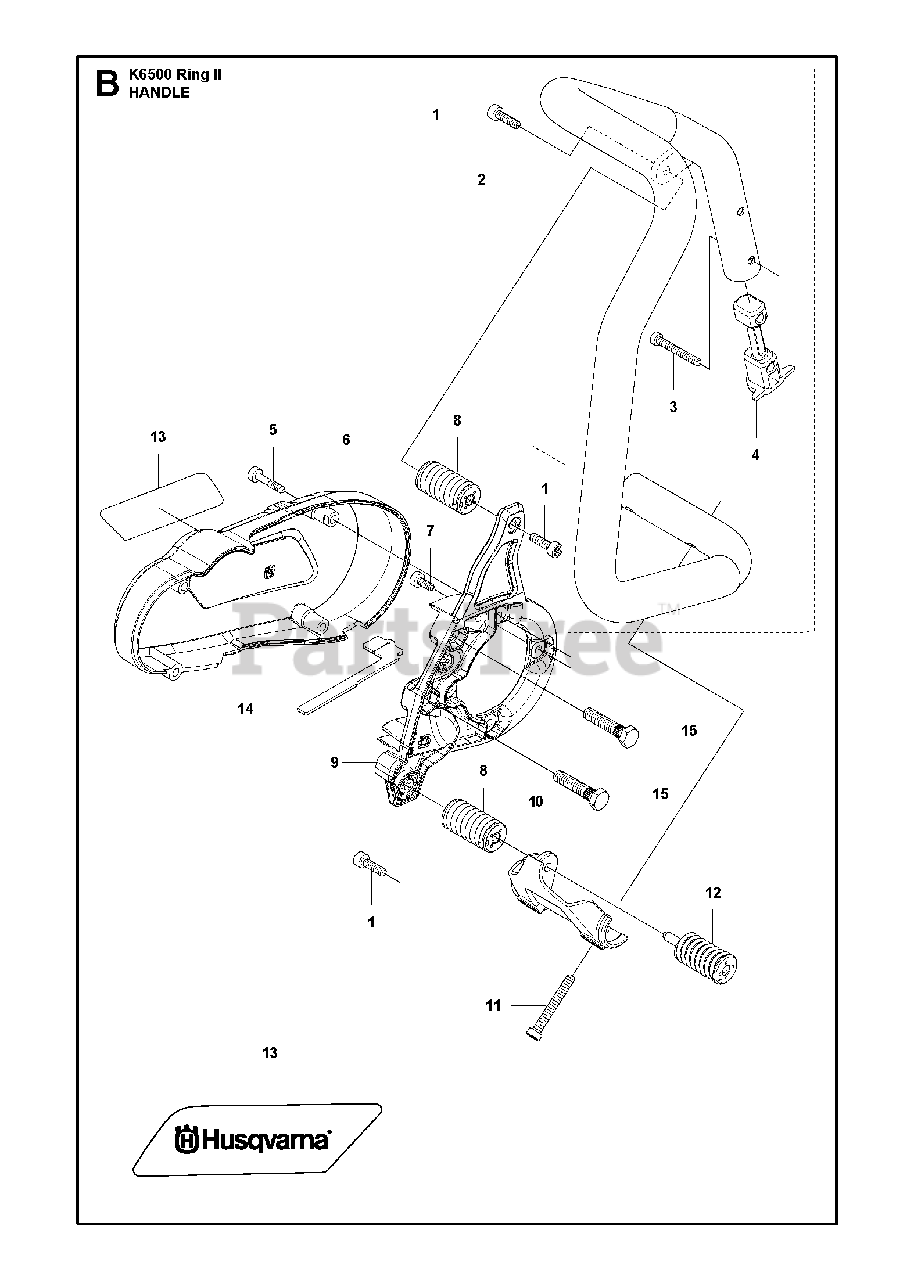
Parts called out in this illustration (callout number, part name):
1	SCREW ITXSCM
5	SCREW ITXSCM
7	SCREW ITXSCM
8	ANTIVIBRATION ELEMENT
11	SCREW ITXSCT
12	ANTIVIBRATION ELEMENT
